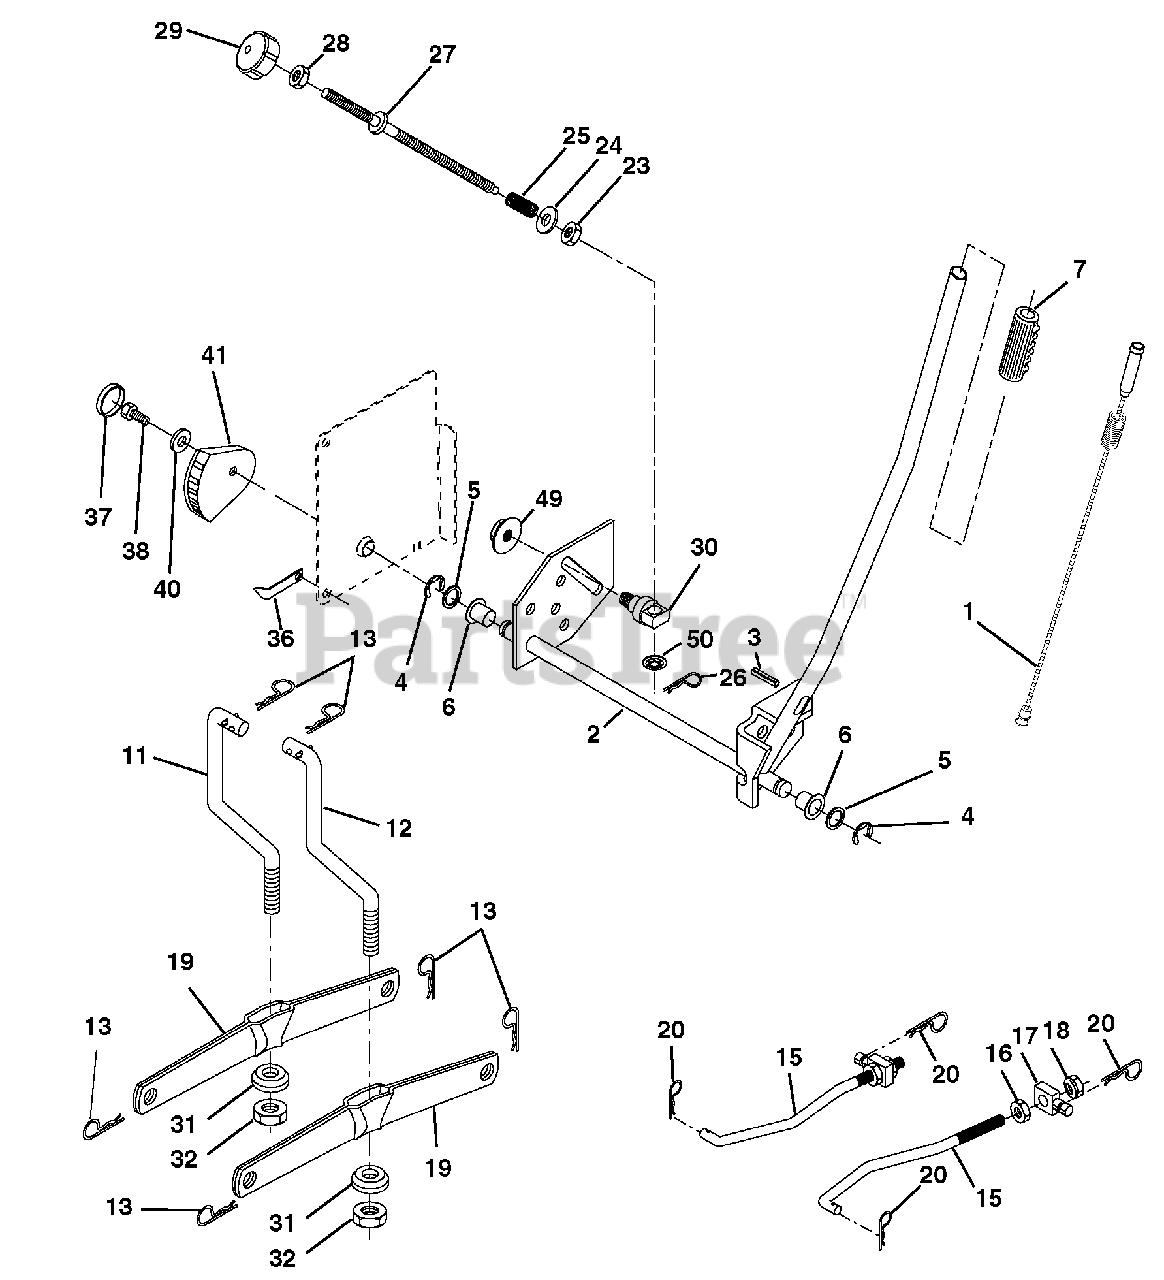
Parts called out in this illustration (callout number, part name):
1	Plunger Asm.
2	Shaft Asm Lift RH w/Inf
3	Pin Groove 2"
4	E Ring #5133-62
5	Washer 21/32 x 1 x 21 Ga.
6	Bearing Nylon Blk 629 Id
7	Grip Handle
11	Link Lift LH Fixed Length
12	Link Lift RH Fixed Length
13	Retainer Spring
15	Link Front
16	Nut Jam Hex 1/2-13 unc
17	Trunnion
18	Nut Lock W/Wsh 1/2-13 unc
19	Arm Suspension Rear
20	Pin Cotter 7/16 Bow Tie Lock
23	Nut Special
24	Washer 13/32 x 5/8 x 16 Ga.
25	Spring
26	Retainer Clip
27	Rod Adj Lift
28	Nut Hex Jam 3/8-16 unc
29	Knob Inf 3/8-16 unc Blk W/sym
30	Trunnion Infin Height
31	Bearing Pvt Lift
32	Nut Crownlock 3/8 - 24
36	Pointer Height Indicator
37	Plug Hole Blk 1.485/1.515 Dia.
38	Screw 5/16-18 x 1
40	Washer 11/32 x 1-1/2 10 Ga.
41	Indicator Height STLT
49	Nut Hex Flange Lock
50	Nut PUsh Phos & Oi
